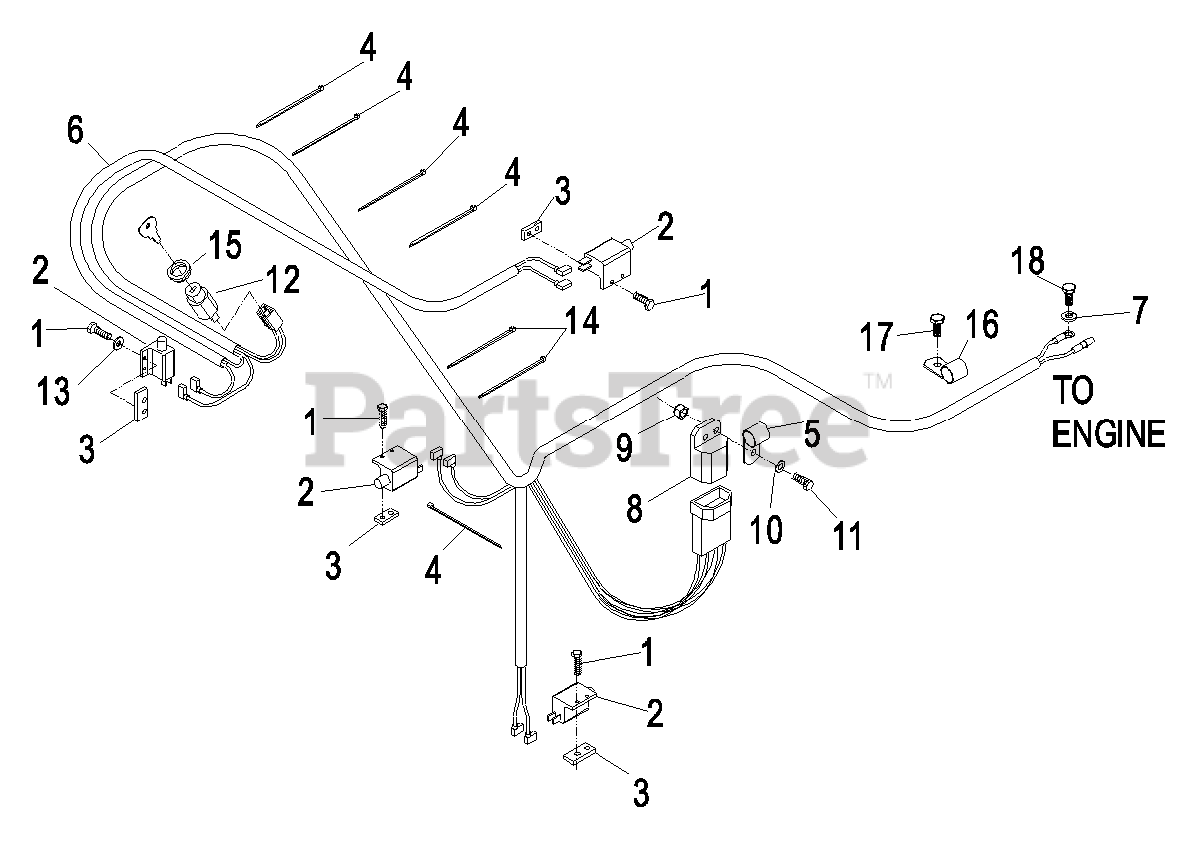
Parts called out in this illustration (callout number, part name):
1	SCREW-PPH
2	SWITCH-OPEN, NORMALLY
3	PLATE-TAPPED
4	TIE-CABLE
5	CLIP-LOOM
6	HARNESS,WIRING KA PULL ST
7	WASHER-LOCK
8	MODULE-INTERLOCK
9	NUT-LOCK, NI
10	WASHER-FLAT
11	SCREW-HH
12	SWITCH & KEY (INCLUDES NU
13	WASHER-FLAT
14	TIE-PLASTIC
15	NUT-SWITCH, IGNITION
16	CLIP-LOOM
17	SCREW-HH
18	SCREW-HH
